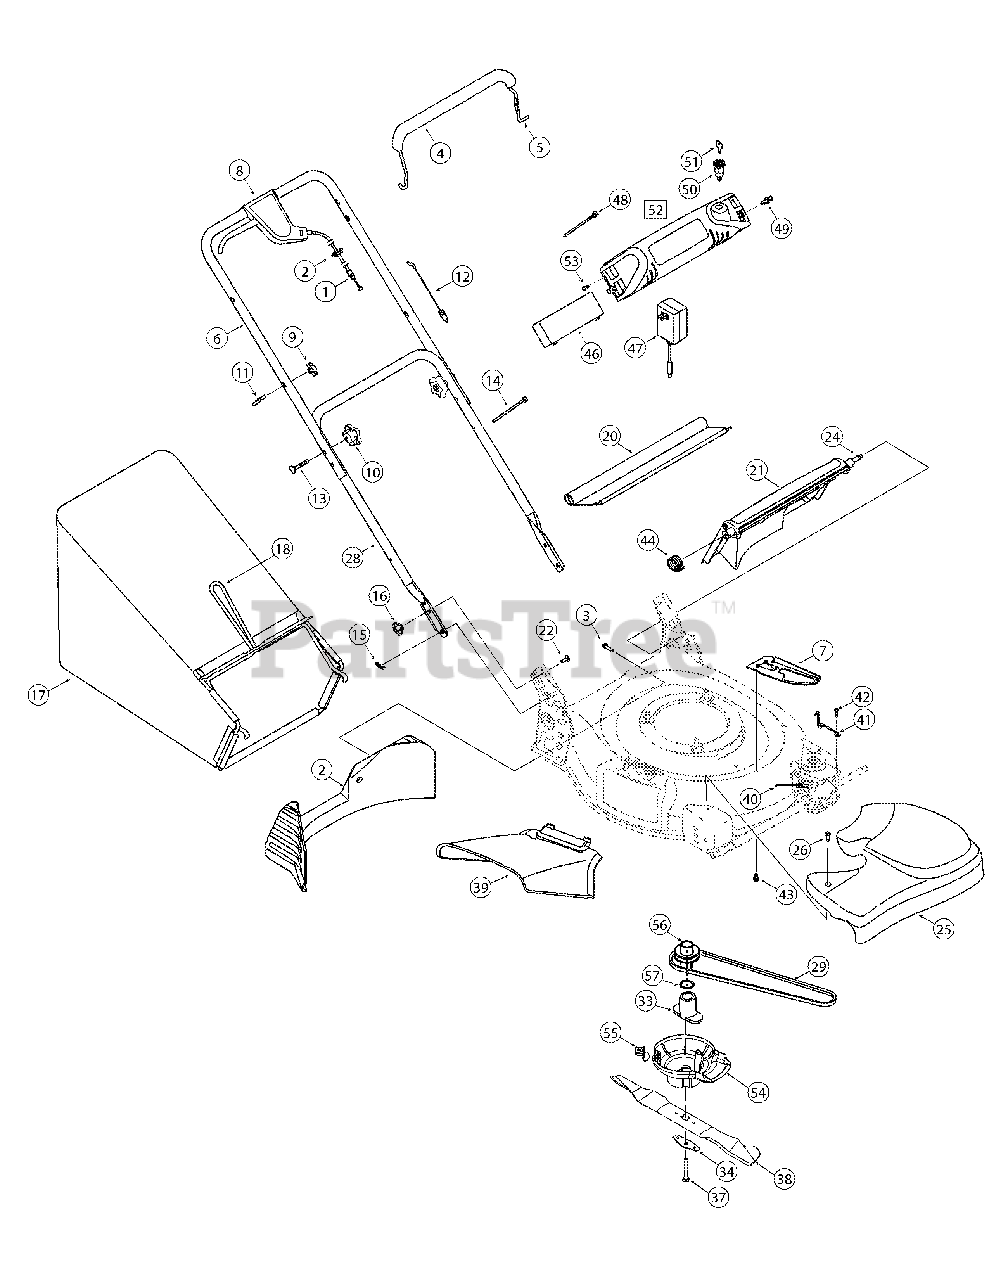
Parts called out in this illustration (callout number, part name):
2	Rear Baffle 21" Rear Discharge
3	Hex Lock Screw 1/4-15 x 1.0
4	Bail Cover - Grey
5	Blade Control Handle
6	Upper Handle
7	Cable Mounting Bracket
8	Control Lever Ass'y
10	Knob - Star 5/16-18
11	Rope Guide Bolt
12	Control Cable 37.25" Lg.
13	Carriage Bolt 5/16-18 x 2.0
14	Cable Tie
15	Int. Cotter Pin .072 x 1.13" Lg.
16	Wing Nut
17	Grass Bag -Generic
18	Grass Bag Frame
20	Trail Shield
21	Rear Discharge Door
22	Carriage Bolt 1/4-10 x .75
24	Pivot Rod (w/12" rear wheels)
25	Trans. Cover (Oyster Grey)
26	Shoulder Screw #12-24
30	Upper Pulley Half 25mm x 2.62
31	Lower Pulley Half 25mm x 2.62
32	Sleeve Spacer 25 mm ID x 1.375 x .375
33	Blade Adapter
34	Blade Bell Support
35	Space Washer
37	Hex Bolt 3/8-24 x 2.5" Lg.
38	21" Mulching Blade
39	Chute Deflector
40	Extension Spring
41	Belt Keeper Wire
43	Screw 1/4-14 x 0.625
44	Torsion Spring RH
46	12V Battery
47	Battery Charger
48	Cable Tie
52	Electric Starter Harness Ass'y
53	Screw, #10-16 x .750
54	Engine Baffle
56	Drive Pulley Ass'y
57	Wave Washer 1.35 x 1.05 x 0.015
